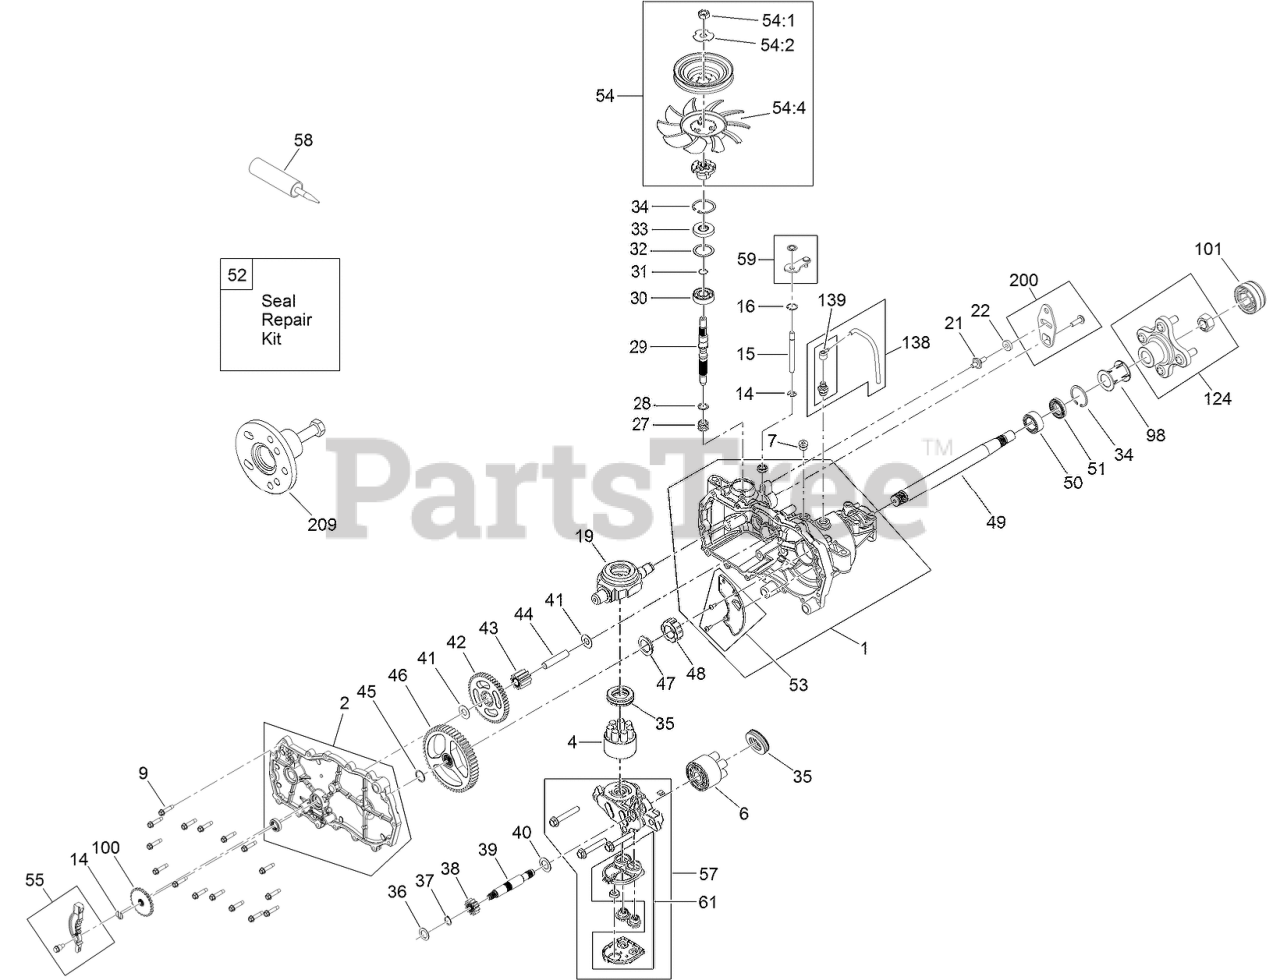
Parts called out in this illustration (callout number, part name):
1	MAIN HOUSING ASM
2	SIDE ASM
4	PUMP BLOCK ASM
6	CYLINDER BLOCK KIT
7	PLUG-THREAD, STRAIGHT
9	SCREW-HHF
14	RING-RETAINING, EXTERNAL
15	ROD-BYPASS
16	RING-RETAINING, INTERNAL
19	SWASHPLATE-TRUNNION
22	PUCK-FRICTION
27	SPRING-BLOCK
28	WASHER
29	SHAFT-INPUT
30	BEARING-BALL
31	RING-RETAINING
32	SPACER
33	SEAL-LIP
34	RING-RETAINING
35	BEARING-THRUST
36	WASHER-FLAT
37	RING-RETAINING
38	GEAR-PINNION, 13T
39	SHAFT-MOTOR
40	WASHER
41	WASHER
42	GEAR-10T/48T
43	GEAR-JACKSHAFT, 10T
44	PIN-JACKSHAFT
45	RING-SPIRAL, RETAINING
46	GEAR-52T, BULL
47	WASHER
48	BEARING-SLEEVE
49	SHAFT-AXLE
50	BUSHING-AXLE
51	SEAL-LIP
52	SEAL KIT
53	EXPANSION PLATE KIT
54	FAN AND PULLEY KIT
54:1	NUT-HJ
54:2	WASHER-SLOTTED
54:4	FAN 7.0 X 10 BLADE
55	BRAKE ARM KIT
57	CENTER SECTION FILTER KIT
58	SEALANT
59	BYPASS KIT
61	FILTER KIT
98	TUBE-AXLE
100	DISC-BRAKE, COG
101	COVER-NUT, AXLE
124	HUB KIT
138	BREATHER KIT
139	BREATHER ASM
200	CONTROL ARM KIT
